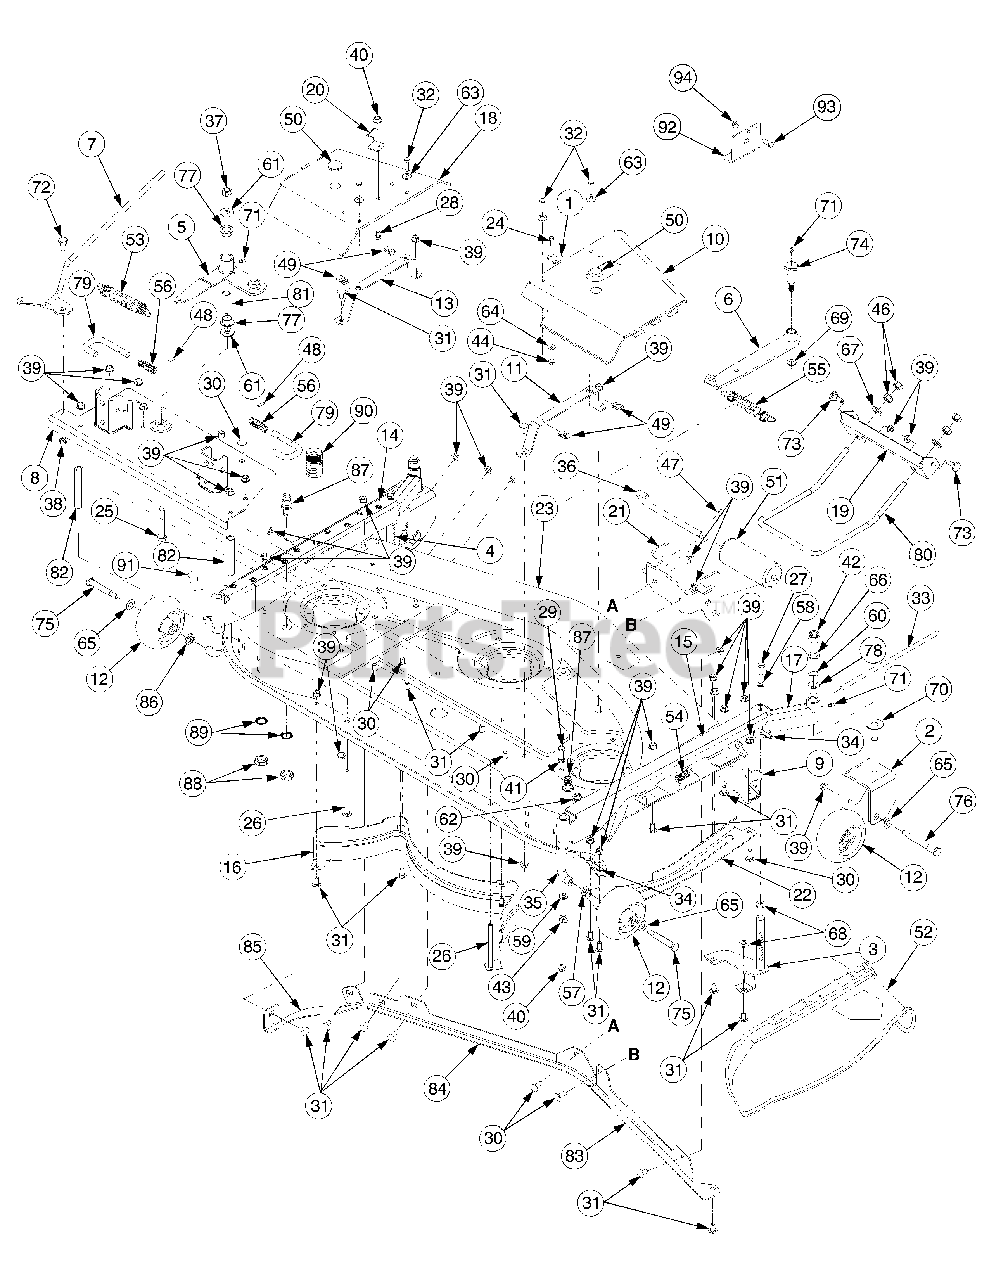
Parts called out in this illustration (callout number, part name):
1	Brackt, Hook Retainer
3	Spindle, Adjustment RH
4	Spindle, Adjustment LH
5	Bracket, Idler
12	Fitting, Lube
12	Bearing, Flange, .503 x .75
23	Deck
24	Screw, Hex Cap 1/4-20 x .62 GR5
25	Screw, Hex Cap, 1/2-20 x 3.0 GR8
26	Carriage, Bolt 3/8-16 x 5.0 GR5
27	Screw, Hex Cap, 3/8-16 x .88 GR5
28	Screw, Hex Cap, 5/16-18 x .5 GR5
29	Screw, Hex Cap, 5/16-18 x 2.25 GR5
30	Carriage, Bolt 3/8-16 x 1.0
31	Carriage, Bolt 3/8-16 x .75
32	Screw, Hex Cap, 5/16-18 x 1 GR5
33	Pin, Hinged .375 x 14.06
33	Pin, Hinged .3175 x 14.06
34	Pin, Clevis w/Ball Detent
35	Axle, Castor
36	Pin, Roller 1/2 x 7.31
37	Nut, Hex Lock, 1/2-20 GRA
38	Nut, Hex Lock, 3/8-16 GRA
39	Nut, Flange Lock 3/8-16
40	Nut, Flange Lock, 5/16-18 GR5
41	Nut, Hex , 5/16-18 GR5
42	Nut, Hex Lock 5/8-11
43	Nut, Hex, 7/16-14 GR2
44	Nut, Hex Flange Lock 1/4-20
46	Nut, Hex, 1/2-13
47	Pin, Cotter 3/32 x 1.25
48	Pin, Spirol
49	Nut, "U" 5/16-18
50	Plug, Button
51	Roller, Front
52	Deflector, Chute
53	Spring, Extension
54	Spring, Torsion
55	Spring, Extension
56	Spring, Compression
57	Washer, Bell, .375 x .87 x .063
58	Washer, Lock 3/8" I.D.
59	Washer, Lock 7/16" I.D.
60	Washer, Wave, .625 x .885 x .015
61	Washer, Flat, .5 x 1.25 x .10
62	Washer, Flat, .535 x .93 x .09
63	Washer, Bell .34" I.D.
64	Washer, Bell .265 x .75 x .062
65	Washer, Flat, .51 x 1.0 x .06
66	Washer, Flat, .625 x 1.0 x .067
67	Washer, Flat, .531 x 1.062 x .134 HT
68	Washer, Flat, .406 x .875 x .105
69	Washer, Flat, .469 x .875 x .105
70	Washer, Flat, 1.595 x .635 x .062 HT
71	Fitting, Lube, 3/16 Drive
72	Screw, Shoulder, .498 x .34: 3/8-16
73	Screw, Shoulder, .5 x .434: 3/8-16
74	Screw, Shoulder, .68 x 1.59
75	Screw, Shoulder, .5 x 2.5
76	Screw, Step Shoulder, 5/8-1/2 x 3.4
77	Bearing, Flange, 3/4 x .52
78	Bearing, Flange, .63 ID
79	Pin, Mower Support
80	Rod, Deck Hanger
81	Spacer, .5 x .75 x 2.07" Lg.
82	Spacer, .405" x .75 x 3.875" Lg.
86	Spacer, Shoulder
87	Nozzle, Deck Wash
88	Nut, Hex, M16-1.5
89	Washer, Lock
90	Adapter, Water Nozzle
91	Plug, Screw, M16-1.5
93	Screw, Hex Cap, 3/8-16 x 1.0 Gr5
94	Nut, Flange Lock, 3/8-16 GrF
